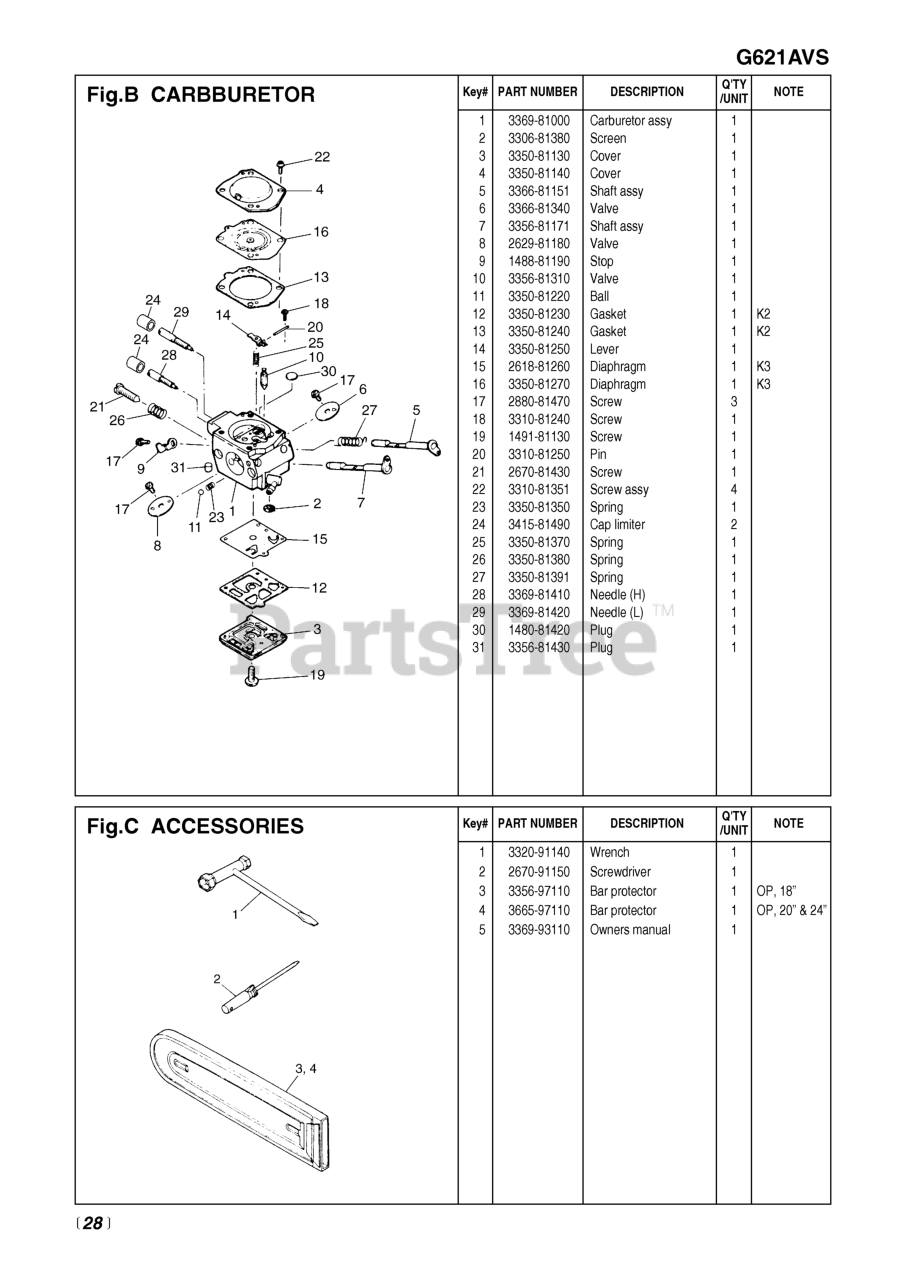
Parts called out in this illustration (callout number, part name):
1	CARBURETOR (HDA-212-1)
4	DIAPHRAGM
6	VALVE, THROTTLE
7	CHOKE SHAFT A
10	VALVE, INLET
11	BALL, FRICTION
15	DIAPHRAGM
16	DIAPHRAGM
17	SCREW (RPLS 3310-81360)
20	PIN, METERING LEVER
22	SCREW ASSEMBLY
23	SPRING
24	CAP, LIMITER
26	SPRING, IDLE
27	SPRING, RETURN
28	NEEDLE (H)
29	NEEDLE (L)
30	PLUG, WELSH
31	PLUG, FRICTION
A1	WRENCH, PLUG
A2	SCREWDRIVER
A3	PROTECTOR (RPLS 3359-97110)
A4	PROTECTOR (RPLS. 3369-97110)
